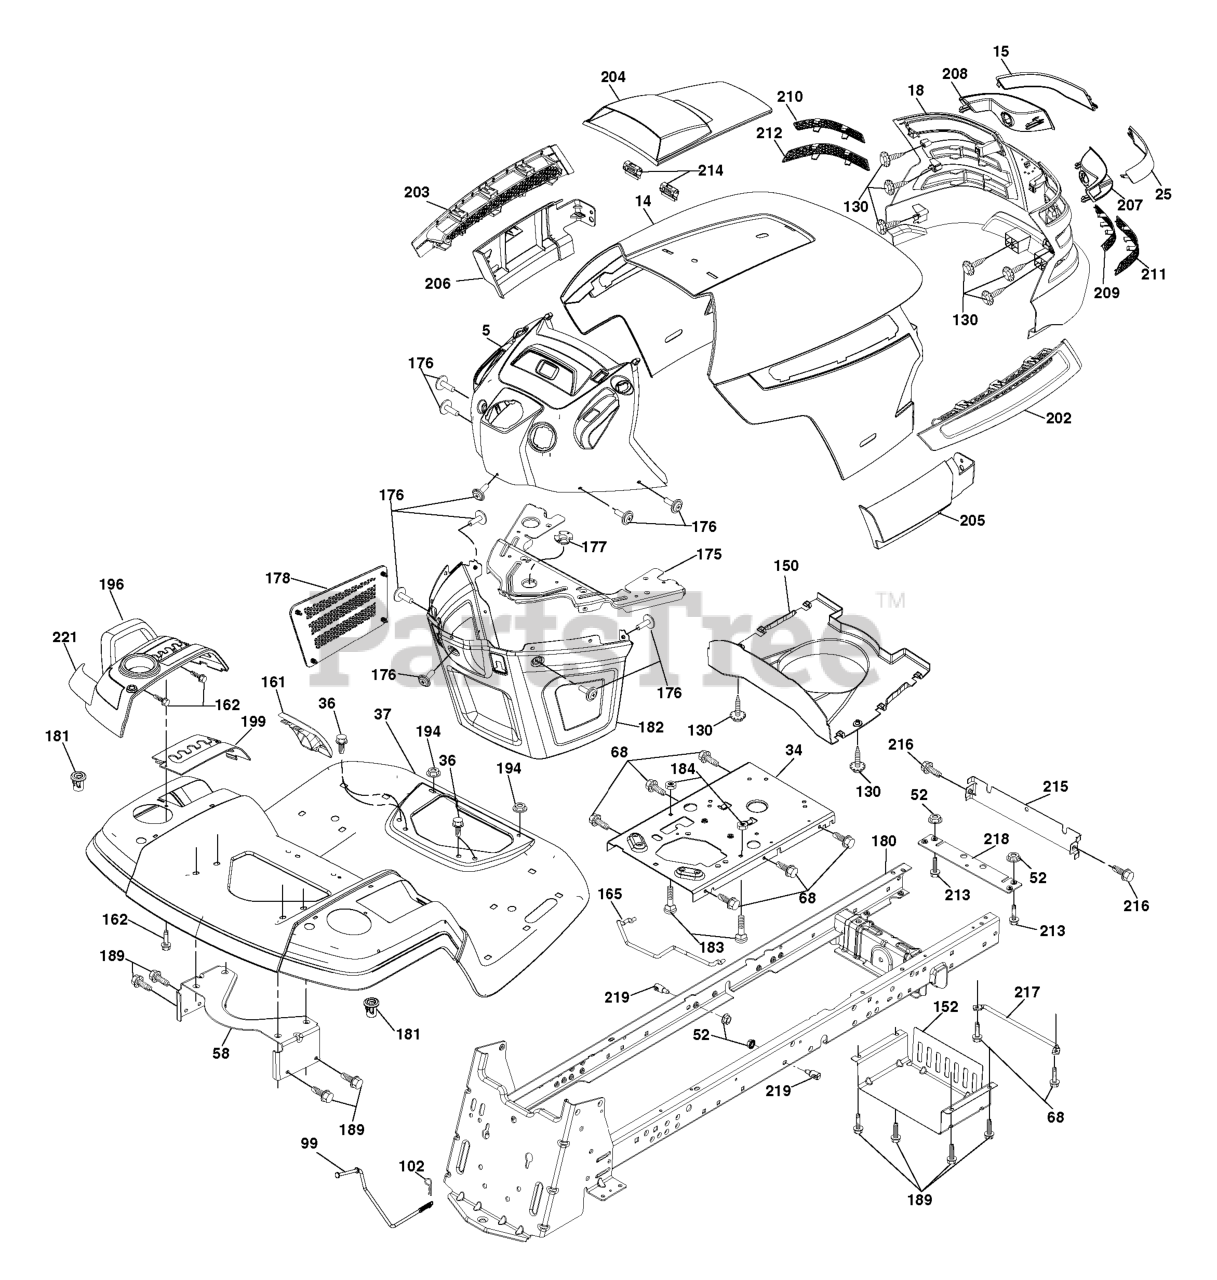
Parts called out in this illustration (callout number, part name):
5	DASH.HUSQ.UPR.ELE.SVMD
14	HOOD.PNT.HUSQVARNA.GT.
15	LENS.LH.TEX.GT.HUSQ.CL
18	GRILLE.ASM.TEX.GT.HUSQ
25	LENS.RH.TEX.GT.HUSQ.CL
34	PLATE.ENGINE.WELDED.CHASSIS
37	FENDER.PNT.TX.GT.CH/FW.ORANGE
52	LOCKNUT
58	BRKT.SUPPORT.FNDR/TANK
68	Screw 5/16-18 x 1/2
99	ROD.BYPASS.K46.TG
102	RETAINER M
130	SCREW
139	BOLT, SHOULDER 5/16-18
150	AIR.DUCT.TEXGT.HUSQ.SV
152	SHIELD.BROWNING.WTEXLT
156	SCREW
161	CONSOLE.FUEL.WINDOW.HU
162	SCREW.HI-LO.CONSOLE
165	SUPPORT.TANK.REAR.W/TEX
175	PLATE.CROSSMEMBER.HUSQ
176	SCREW.#10-24X5/8.RN.QU
177	BUSHING, STEERING
178	CARGO.ASM.NET.TXGT.W/C
180	CHASSIS.WLDMT.TX.GT.05
181	BUSHING.MNT.FEND.CRGO.
182	DASH.LOWER.COMMON.12V.
184	SPACER.FENDER
185	BOLT.CARRIAGE.5/16-18
189	SCREW
194	NUT LOCK HEX FLANGE 5/16-18
196	RP CONSOLE.ASM.DECKLFT.W/
199	PLATE.DECK.LIFT.HUSQVARNA.GT
202	VENT.SIDE.HOOD.HUSQ.RH.GREY
203	VENT.SIDE.HOOD.HUSQ.LH.GRAY
204	VENT.TOP.HOOD.HUSQVARN
205	SKIRT.HOOD.SIDE.HUSQ.RH.GREY
206	SKIRT.HOOD.SIDE.HUSQ.LH.GREY
207	BEZEL.RH.TEX.GT.HUSQ
208	BEZEL.LH.TEX.GT.HUSQ
209	INSERT.HEX.GRILL.HUSQ.GREY
210	INSERT.HEX.GRILL.HUSQ.
211	INSERT.HEX.GRILL.HUSQ.
212	INSERT.HEX.GRILL.HUSQ.
213	BOLT
214	CLIP.RETAINER.TINNER.
215	COVER.CHASSIS.FRONT.WE
216	SCREW, 5/16-18 X 1/2
217	ROD PIVOT CHASSIS/HOOD
218	X-PIECE.HOOD.STOP.NON/
219	STUD.FASTNER.W/ANTI-ROTATE
221	REFLECTOR.LH.TEX GT HU
